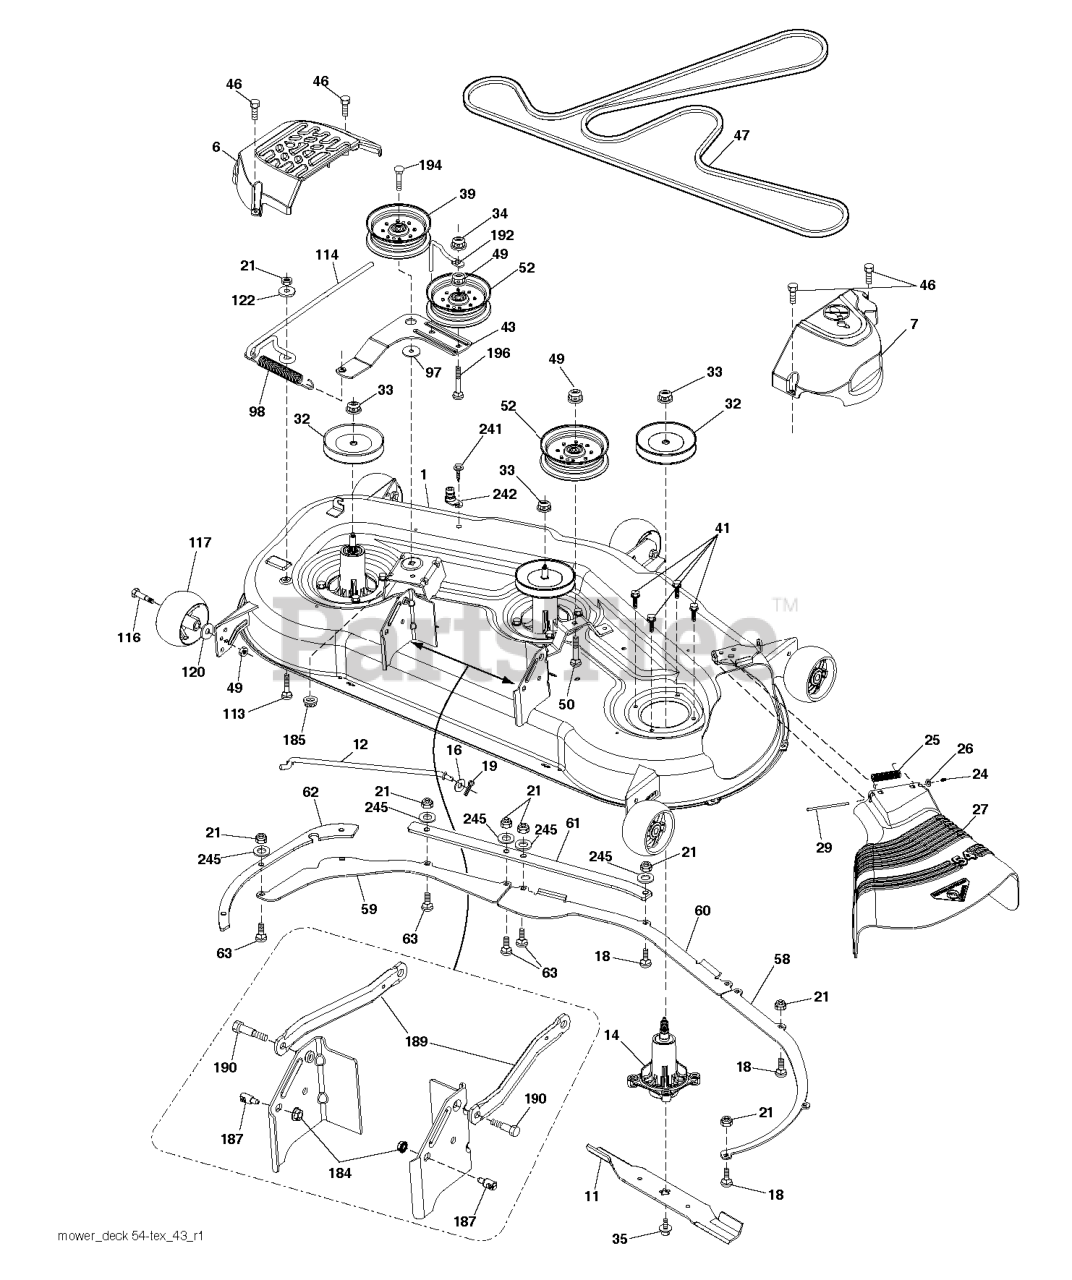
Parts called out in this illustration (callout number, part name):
1	DECK SVC 54"
6	COVER.MANDREL.LH.54"20
7	COVER.MANDREL.RH.54.20
11	BLADE.BAGGING.54"
12	ROD.ANTI.SWAY.48/54"K4
13	SHAFT ASSY, MANDREL SHAFT
14	RP.HOUSING.MANDREL.4PT.
15	BEARING.MANDREL.TOP.EXTENDED
16	WASHER
18	BOLT
19	PIN.COTTER.5/16.BOW TI
21	LOCKNUT
24	CAP-SLEEVE LT
25	SPRING, TORSION
26	NUT PUSH M
27	DEFLECTOR
29	ROD.HINGE
32	PULLEY/MANDREL
33	NUT.FLANGE.LOCK.TOP
35	SCREW.SEMS.7/16-20X1.HEX.HEAD
39	RB PULLEY.IDLER.4.50/HUB SPEC
41	BOLT.HEX.WASHR.HED.313-18X1.19
43	ARM.IDLER
46	SCREW.1/4-20X5/8
47	BELT.DECK.DRIVE.BELT.54
49	NUT LOCK FLG 3/8-16 UNC
50	BOLT
52	PULLEY.IDLER.2006
58	BAFFLE.RIGHT.54"
59	BAFFLE.LEFT.54"
60	BAFFLE CENTER 54" MOWER
61	PLATE.REIN.FRONT.BOLT54"X431
62	PLATE.REIN.SIDE.BOLT.54"X431
63	BOLT.CARRIAGE.5/16-18
98	SPRING, DECK DRIVE
113	RHSSNB 5/16C X 1.0
114	ROD TENSION RELIEF
116	BOLT.SHOULDER.3/8-16X3-5/8.
117	WHEEL.GAUGE.RALLY
120	WASHER
122	BUSHING.RELIEF.TENSION
184	NUT LOCK HEX FLANGE 5/16-18
185	NUT.LOCK.FLANGE.7/16
187	STUD.FASTNER.W/ANTI-ROTATE
189	ARM.SUSPENSION.MOWER
190	BOLT.SHOULDER
192	KEEPER.BELT.IDLER.54"T
194	BOLT.HEX.WASHER.HEAD.7/16-24X
196	CARRIAGE BOLT 3/8-16 X
241	SCREW.TT.#10-32X.5.3/8.FLANGE
242	PORT.WASHOUT
245	WASHER
